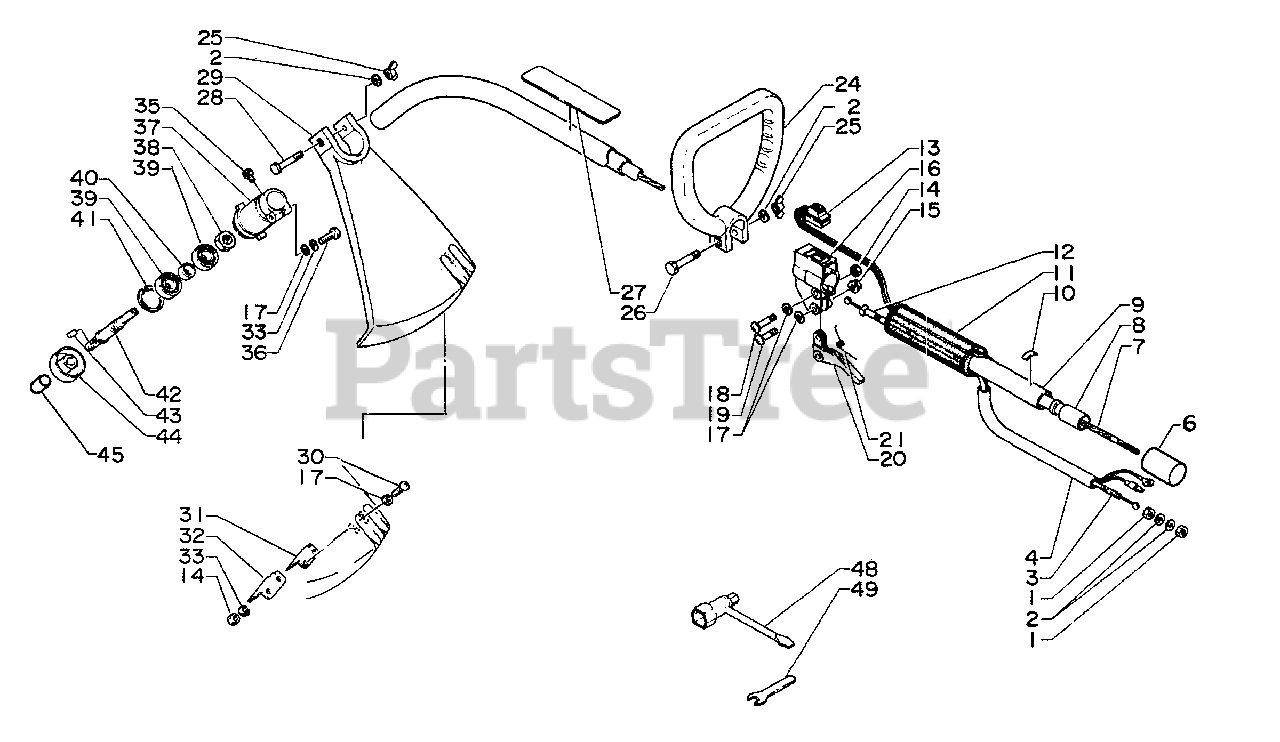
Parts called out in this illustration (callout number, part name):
2	WASHER 6.5×11.5×0.8
3	CABLE, THROTTLE
4	TUBE
7	DRIVESHAFT - FLEXIBLE
8	BUSHING
9	PIPE, MAIN
10	LABEL - ALIGNMENT
11	GRIP, HANDLE
12	GUIDE, CABLE
13	IGNITION SWITCH ASSY
14	NUT M5
15	LOCKNUT - 5
16	BRACKET, THROTTLE
17	WASHER, FLAT 5.5×10×0.8
18	SCREW 5×30
20	TRIGGER, THROTTLE
21	SPRING, THROTTLE
24	HANDLE ASSY
25	NUT, WING 6
26	BOLT - 6×40
27	LABEL - CAUTION
28	BOLT - 6×50
29	SHIELD
30	SCREW 5×14
31	KNIFE, TRIMMER LINE
33	WASHER, SPRING 5
35	SCREW 4×10
36	BOLT - 5×25
37	CASE, GEAR
38	NUT 12 L.H.
39	BEARING, BALL 6001 DDU
41	RING, SNAP 28
42	SHAFT, GEAR
44	PLATE, ADAPTER - UPPER
48	WRENCH
